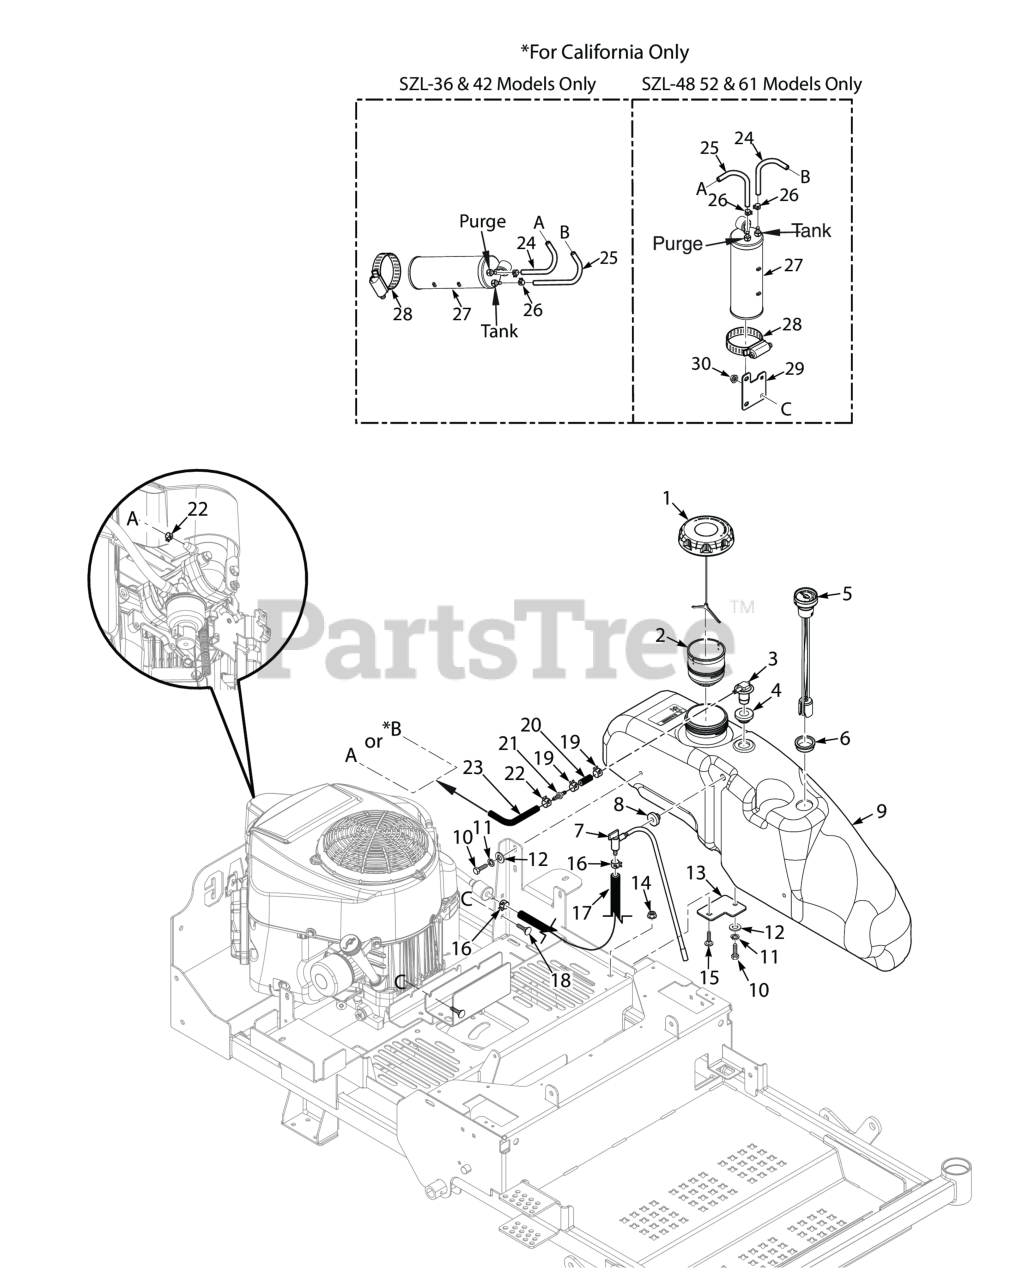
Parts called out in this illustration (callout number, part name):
1	Fuel Cap w/ Tether (E.P.A.)
2	TUBE, FUEL INLET - 3.00
3	Remote Vent, No Valve
4	Grommet, Viton,
5	Fuel Gauge (requires #6)
6	Grommet, Fuel Gauge
7	Valve, Fuel Shut Off
8	Bushing, 0.56" Dia. Viton
9	Fuel Tank Assembly SZL-48, 52 & 61
10	BOLT, SERRATED FLANGE HEX HEAD 5/16-18 X 3/4"
11	Lockwasher, 5/16 (.317 x .586 x .078) Helical Spring
12	Flatwasher, 5/16-.375 x .875 x .083 (35BV & 37BV-EFI)
13	Mounting Bracket, Fuel Tanks Front
14	Nut, Serrated Flange 5/16-18 (Right Front Engine Mounting, Briggs and Kohler Only)
15	Bolt, 5/16-18 x .75 RHSN Carriage
16	Clamp, Fuel Hose 1/4" Hose I.D.
17	Fuel Hose, 1/4" I.D. Non-Perm (791DFI Fuel Return) - Order by Inch
18	Serr. Fl. Hex Head CPSCR, 1/4-20 x 3/4"
19	CLAMP, FUEL HOSE(KAWASAKI ONLY)
20	Hose, 1/4" Vapor Recovery (order by inch)
21	Mender, 1/4 x 3/16 w/0.02 Hole
22	Clamp, Vapor Recovery Hose 3/16"
23	Hose, Vapor Recovery 3/16" (order by inch)
24	Hose, Vapor Recovery 3/16" (order by inch)
25	Hose, Vapor Recovery 3/16" (order by inch)
26	Clamp, Vapor Recovery Hose 3/16"
27	Carbon Canister - SVR-36A / SVR-48V
28	Clamp, 3-1/2" Max. Dia.
29	Bracket, Cannister Mount
30	NUT, 1/4-20 SERRATED FLANGE HEX HEAD
